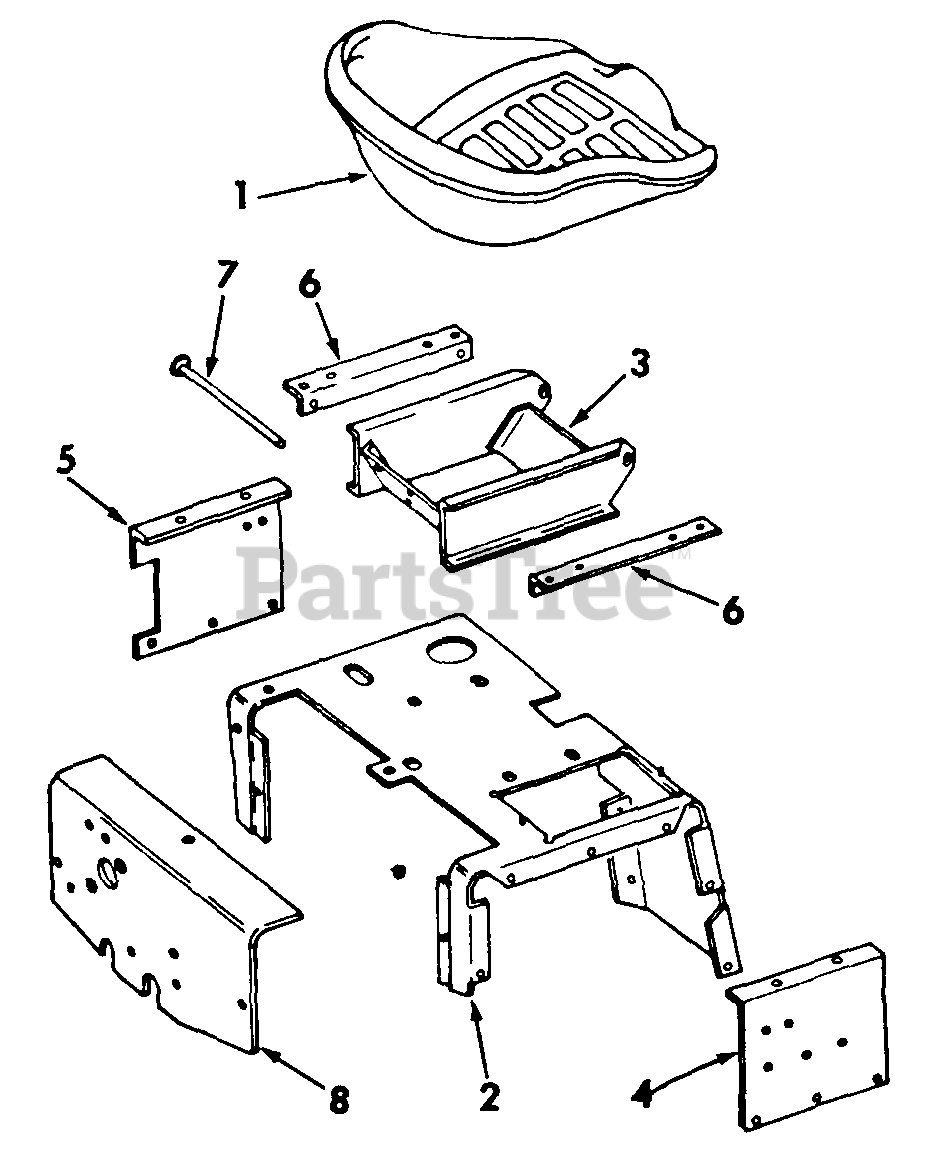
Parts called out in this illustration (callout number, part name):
1	SEAT ASSY, W/O RAILS
2	SHIELD ASSY, REAR FRAME & SEAT SUPPORT
3	SUPPORT ASSY, TOOL BOX & SEAT
4	SHEET ASSY, SEAT SUPPORT LH
5	SHEET ASSY, SEAT SUPPORT RH
6	RAIL, SEAT SUPPORT
7	PIN, SEAT PIVOT
8	COVER ASSY, REAR FRAME
